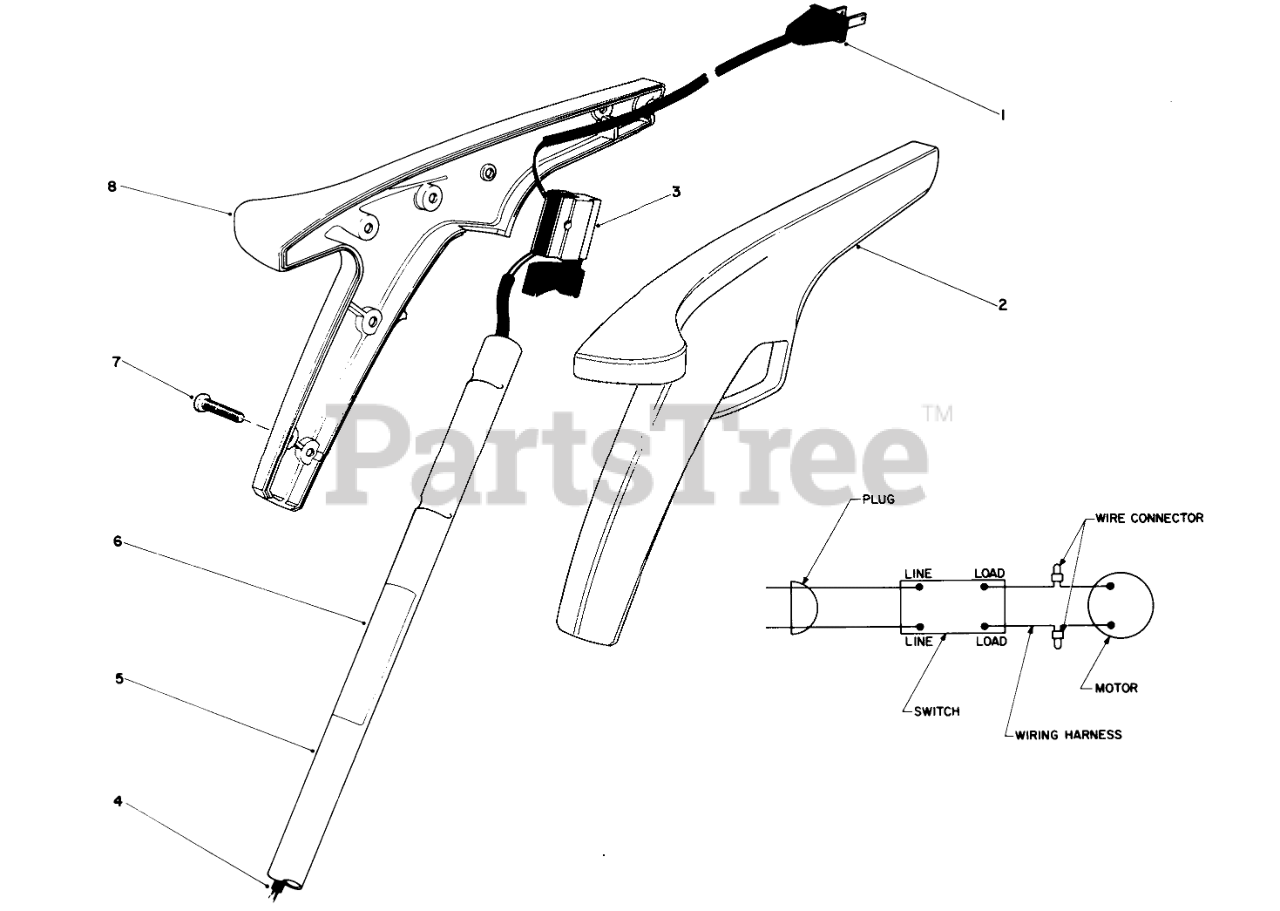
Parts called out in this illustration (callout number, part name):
1	Power Cord
2	LH HANDLE GRIP, 910
3	SWITCH SINGLE SPEED
4	WIRE HARNESS
5	TUBE EXTENSION
6	Decal-Serial (Canada)
7	#8 X .625" PHILPS PAN H
8	Grip-R.H.
